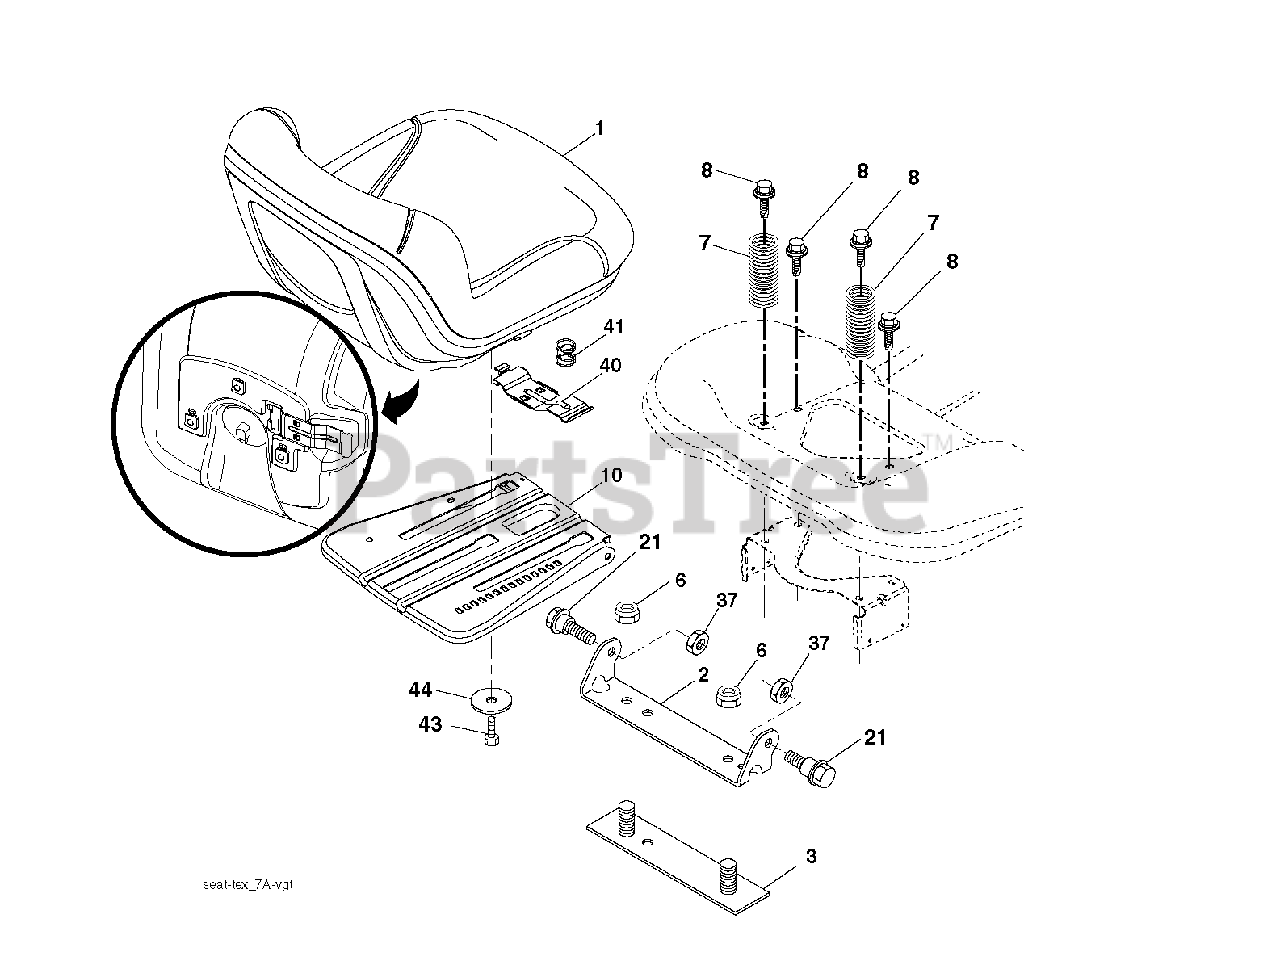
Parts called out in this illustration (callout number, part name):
1	SEAT.TG130.BLACK.NO/LOGO.
2	BRKT.PIVOT.FENDER
6	NUT
7	SPRING COMPRESSION
8	BOLT, 5/16-18 X 1 3/4
10	PAN.ASM.SEAT.3PT
21	BOLT.SHOULDER.5/16-18
37	NUT.71038.31-18.HEX.NYLOCK
40	HANDLE.SLIDE.SEAT.TEX.BLACK
41	SPRING.LATCH.SEAT.TEX
44	WASHER 13/32 X 2-3/8 X 12GA
